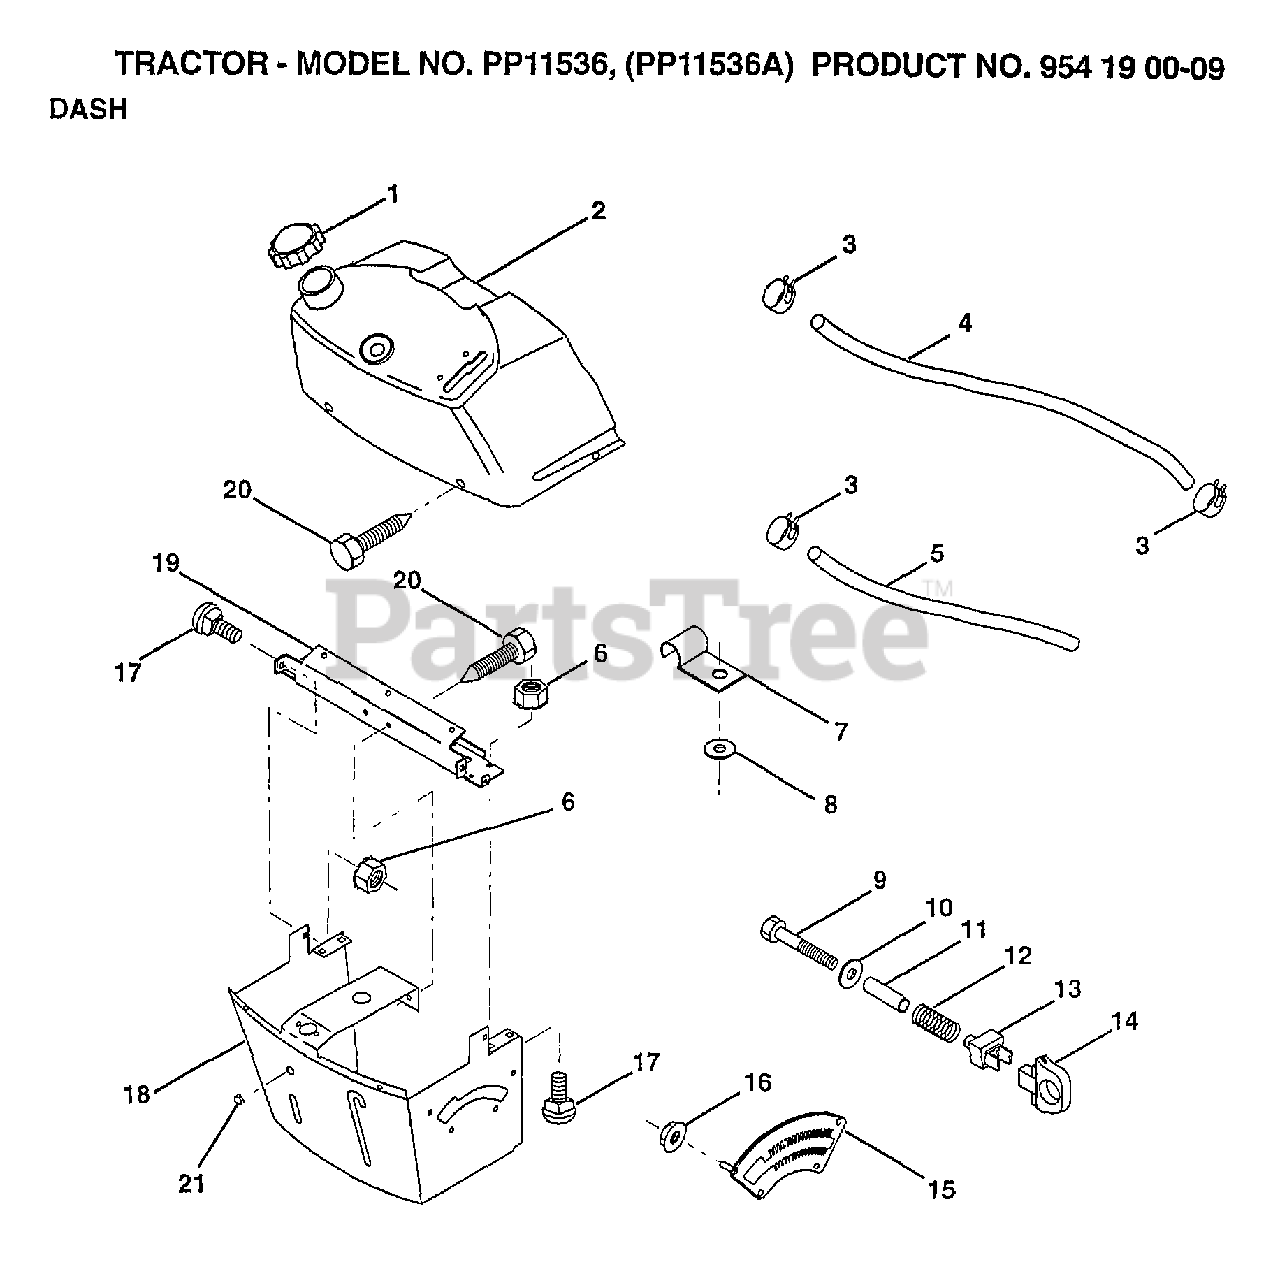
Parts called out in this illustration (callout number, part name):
1	CAP BLK FUEL LR
2	TANK.ASM.DASH.LR
3	HOSE CLAMP
5	FUEL LINE T
6	NUT HXKEP 1/4X20
7	CLIP T
8	WASHER PM
9	BOLT
11	SPACER SPLIT
12	SPRING M
13	"KNOB,HGT RETAINER"
14	KNOB
15	ADJUSTER QUAD
16	NUT
17	BOLT
18	SUPT ASSY DASH
19	CROSS BRACE
20	SCREW.1/4-20X1/2
21	PLUG DOME
